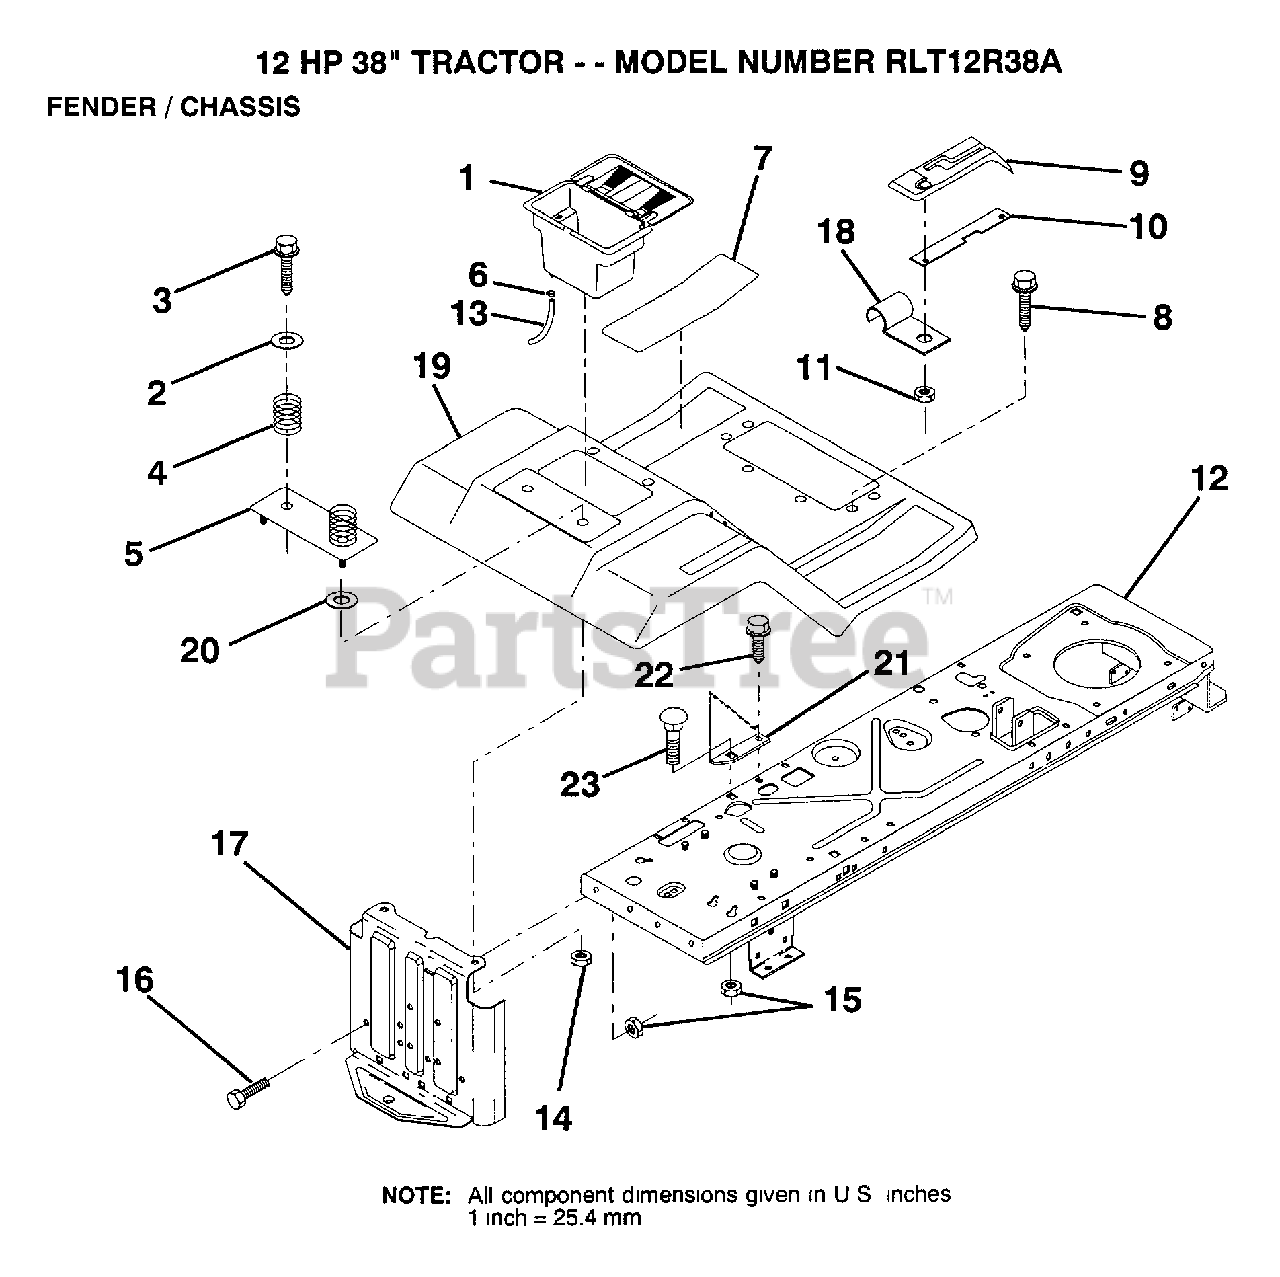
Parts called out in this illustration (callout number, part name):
2	WASHER
3	SCREW
4	SPRING COMPRESSIO
5	"PLATE, BATTERY"
6	HOSE CLAMP T
7	PAD FOOTREST
8	SCREW
10	"SHIFT LOCK, BAR"
11	NUT
14	NUT
16	BOLT
17	DRAWBAR
18	"CLIP,INSULATOR"
22	SCREW LT
